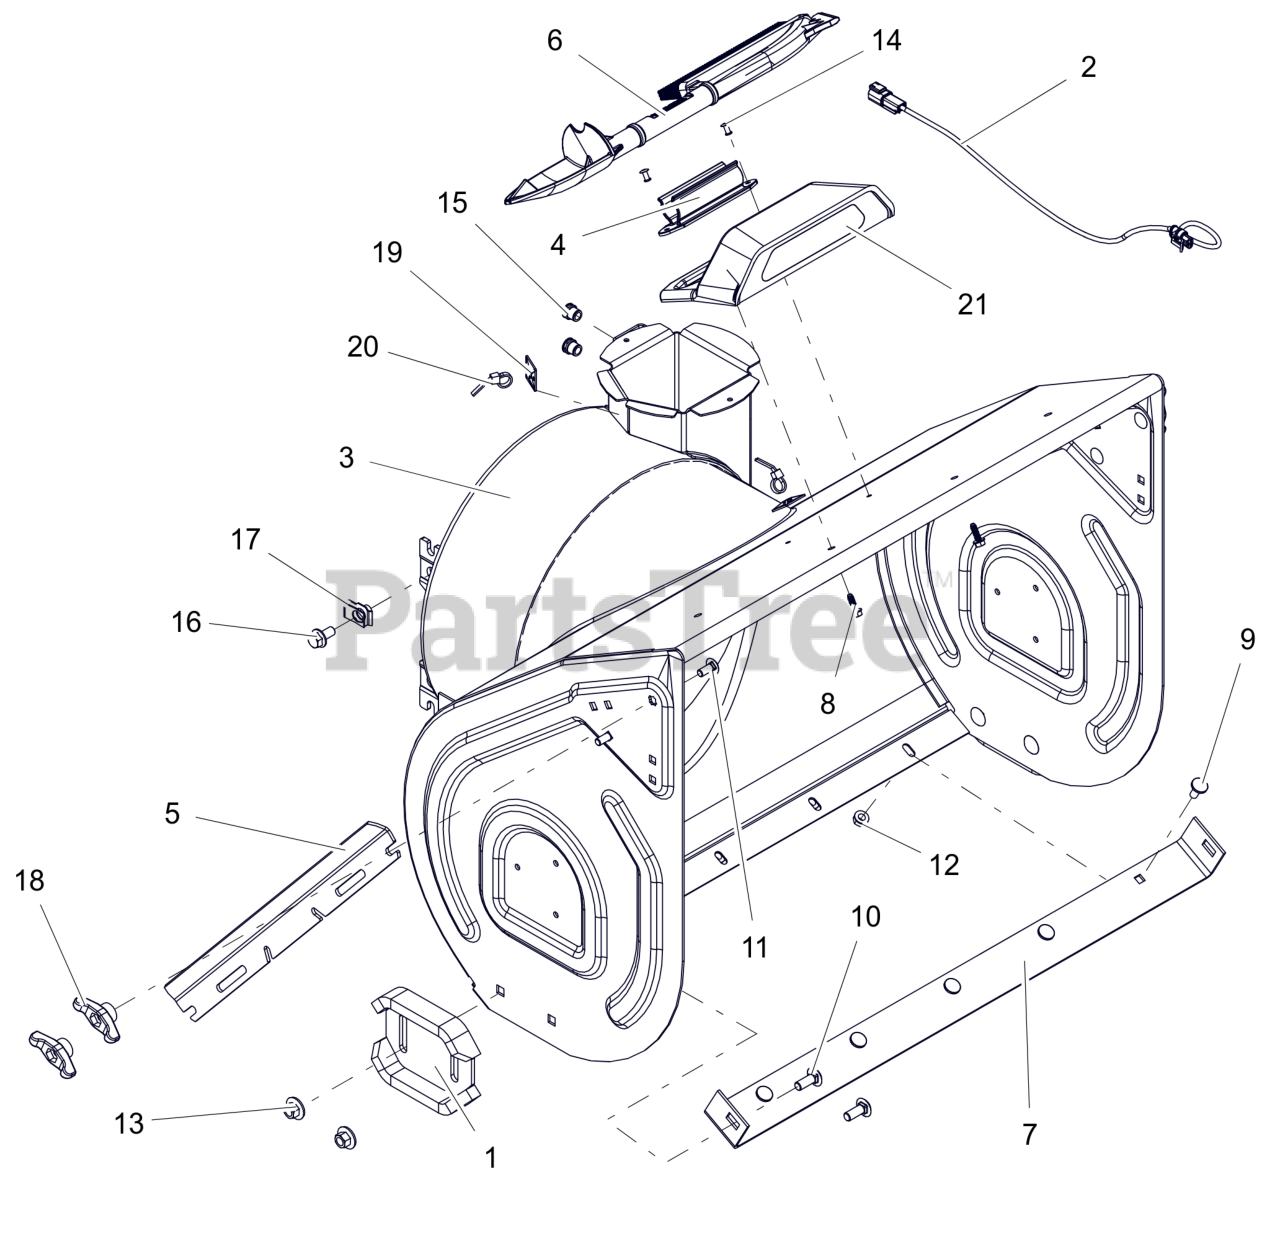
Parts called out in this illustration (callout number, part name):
1	RUNNER, SKID SHOE
2	HARNESS- WIRE - LIGHT JUMPER
3	HOUSING, PRO W/DECAL 28"
4	MOUNT, SNOW CLEAN OUT
5	CUTTER, DRIFT
6	DEVICE, SNOW CLEAN OUT W/BRUSH
7	BLADE, SCRAPER-28"
8	SCR, PLASTITE .25-10X.75 ZCC
9	BOLT, MODIFIED HEAD CARRIAGE
10	BLT,RHSSN .38-16X1.00 G5 ZCC
11	BLT, RHSSN.31-18X.750 G5 ZCC
12	NUT-LK-TOP-FLG .312-18 GF ZCC
13	NUT- CON-LN .375-16 ZC120
14	RIVET, #66 STEEL POP PD BLACK
15	NUT,THD,INSERT .38-16 ZC120
17	NUT-RTNR .375-16X.37
18	KNOB,WING .31-18 UNC NYL/TALC
19	MOUNT, CABLE-TIE DOWN
20	CABLE TIE LG 5-1/2
21	HOUSING, LIGHT - LED
